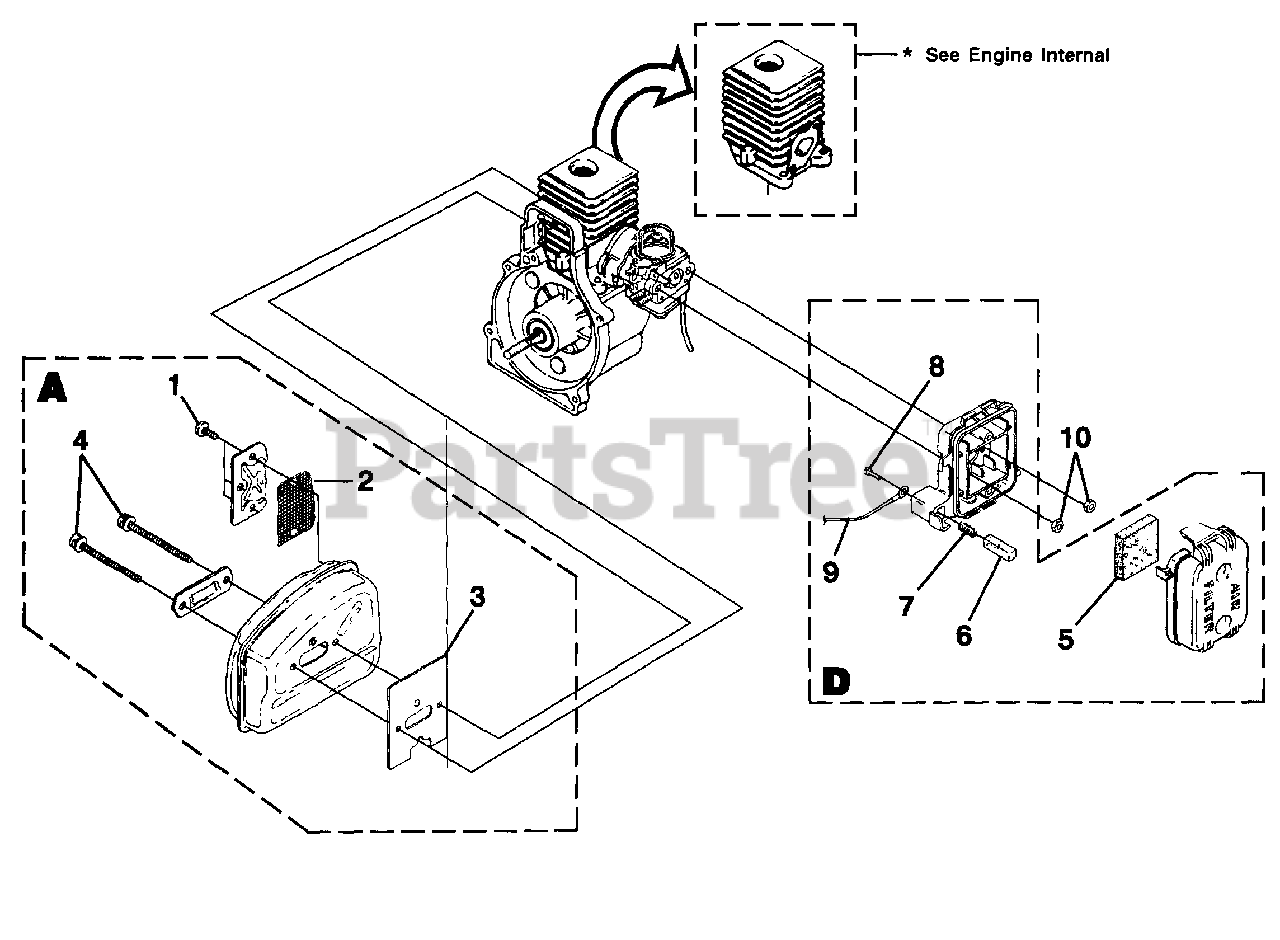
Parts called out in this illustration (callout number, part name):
1	SCREW, Taptite - (8-32 X 3/8")
2	SCREEN-Spark
3	GASKET-Muffler
4	SCREW, Truss Hd. - (10-24 X 2.188)
5	FILTER-Air
6	BUTTON-Switch
7	SPRING-Compression
8	SCREW-Thread Form (6-19 x 1/2")
9	LEAD-Electrical
10	NUT-Hex (10-24)
A	MUFFLER ASSY.
D	AIR FILTER KIT
